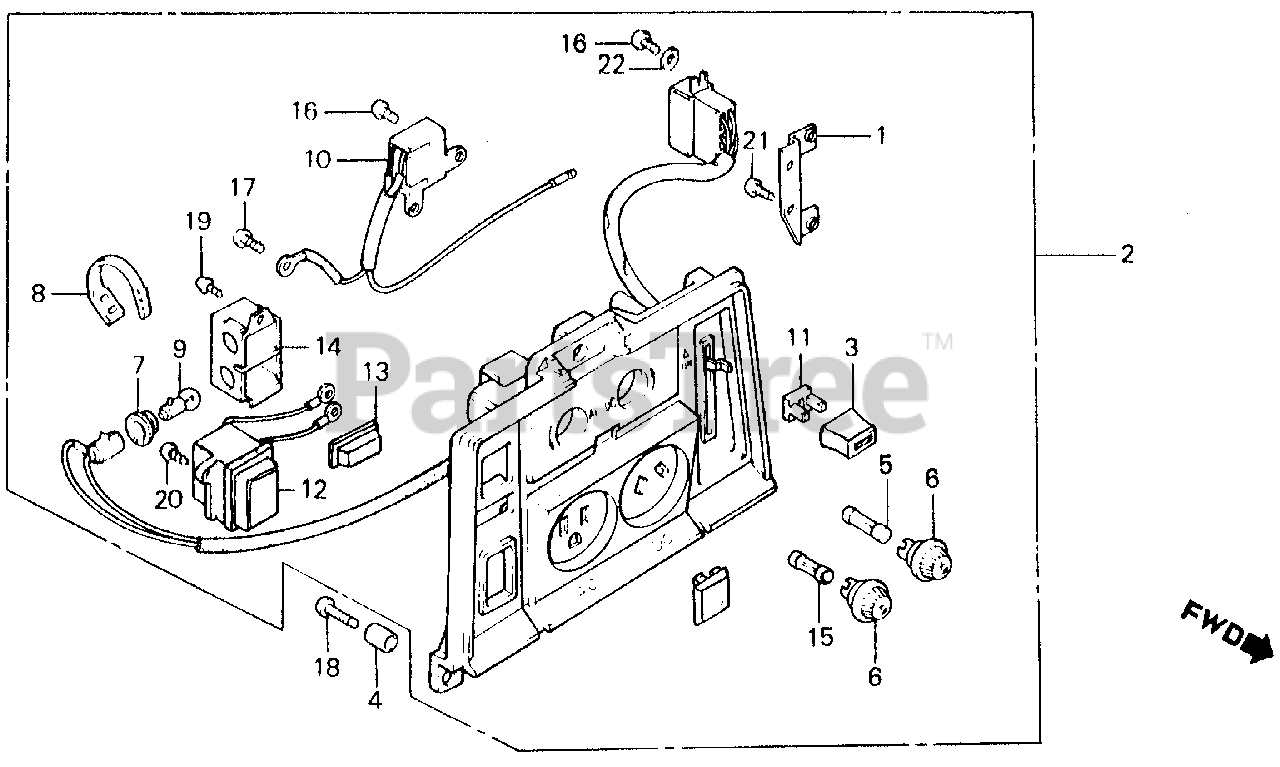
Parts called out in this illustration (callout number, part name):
1	STAY, CONNECTOR
2	PANEL ASSY.
2	PANEL ASSY. (NOT AVAILABLE)
3	KNOB, VALVE LEVER
4	COLLAR, PANEL
5	FUSE B (10A)
6	HOLDER, FUSE (NOT AVAILABLE)
9	BULB, DASH (6V3W) (STANLEY)
10	SWITCH ASSY., STOP (NOT AVAILABLE)
11	BUSH, CONTROL KNOB
12	METER, FREQUENCY
13	LENS, PILOT LAMP (NOT AVAILABLE)
14	CASE, LAMP
15	FUSE (4.5A) (NOT AVAILABLE)
16	SCREW, PAN (3X8)
17	SCREW, PAN (3X10)
18	SCREW, PAN (5X12)
19	SCREW, TAPPING (3X6)
20	SCREW, TAPPING (3X12)
21	SCREW, TAPPING (4X20)
22	WASHER, PLAIN (3MM)
